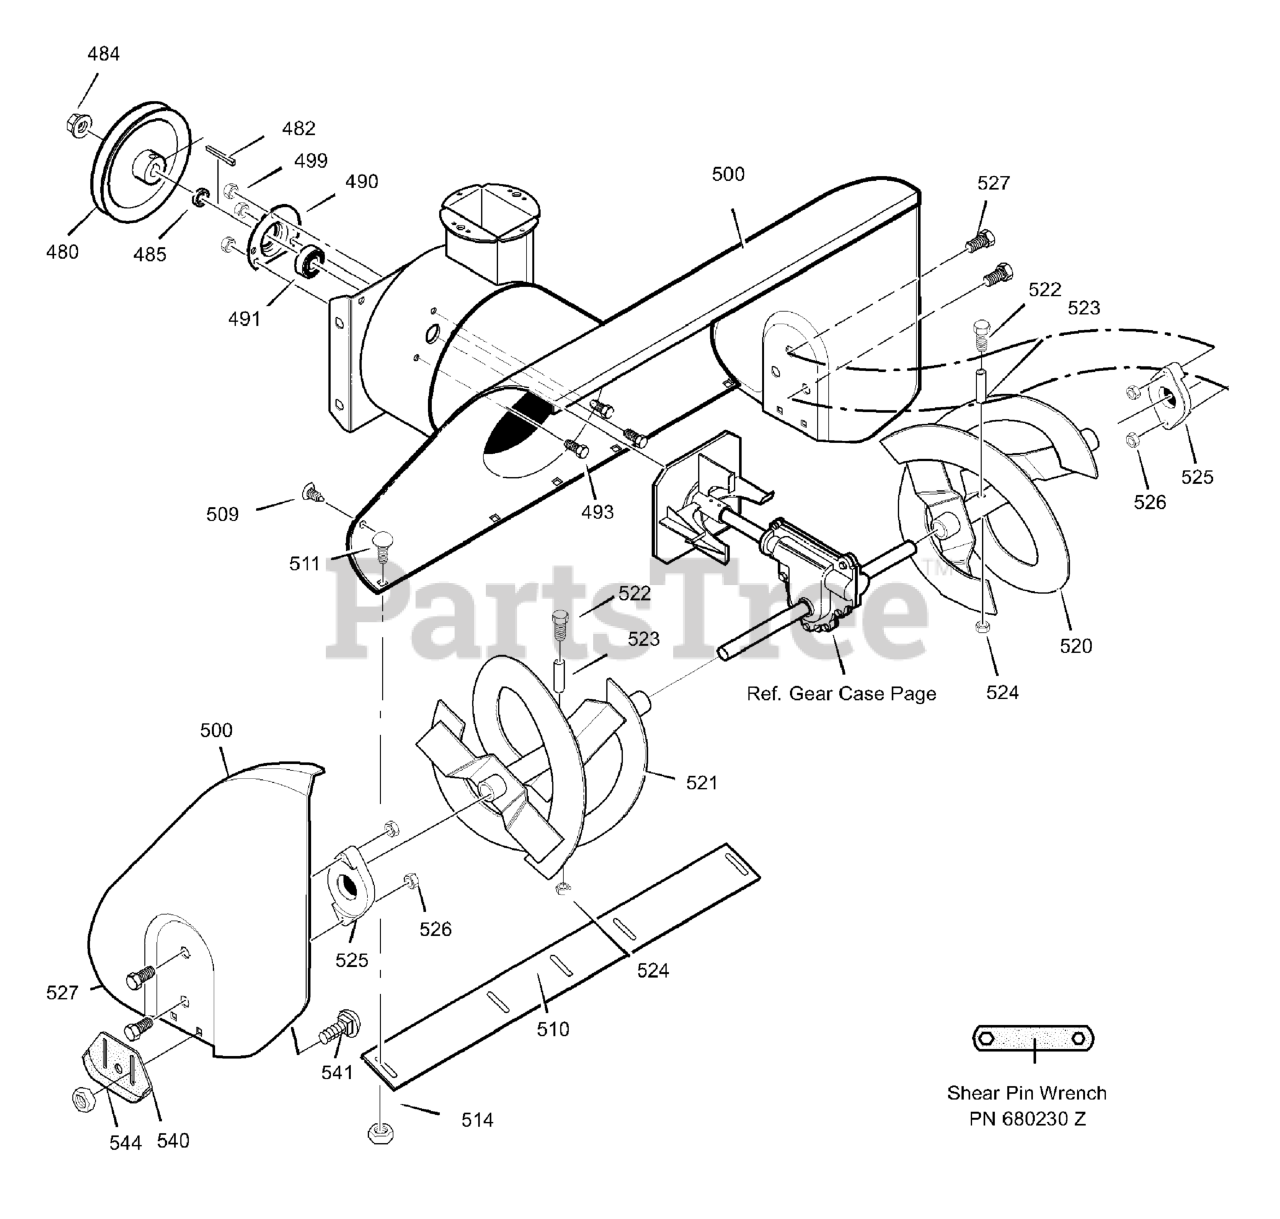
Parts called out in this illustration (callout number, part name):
480	PULLEY, 4L 8.40 OD.
482	KEY, SQUARE 3/16 X 3/4
484	NUT, .50-20 HEXWDFLLK
485	SPACER, FRICTION PULLEY
490	RETAINER, BALL BRNG
491	BEARING, BALL
493	BOLT, HEX 5/16-18X .50
499	NUT, 5/16-18 HEXWDFLLK
500	HOUSING, ASSY
509	FASTENER, RATCHET
510	BLADE, SCRAPER 29"
511	BOLT, 1/4-20X.75
514	NUT, 1/4-20
520	AUGER, ASSY, LH
521	AUGER, ASSY, RH
522	SCREW, 1/4-20X1.75
523	SPACER, SLEEVE
524	NUT, 1/4-20
525	BEARING, FLANGE
526	NUT, 5/16-18
527	SCREW, 5/16-18 x 0.75
540	SKID, HEIGHT ADJUST
541	BOLT, 5/16-18 X .75
544	NUT, 5/16-18
